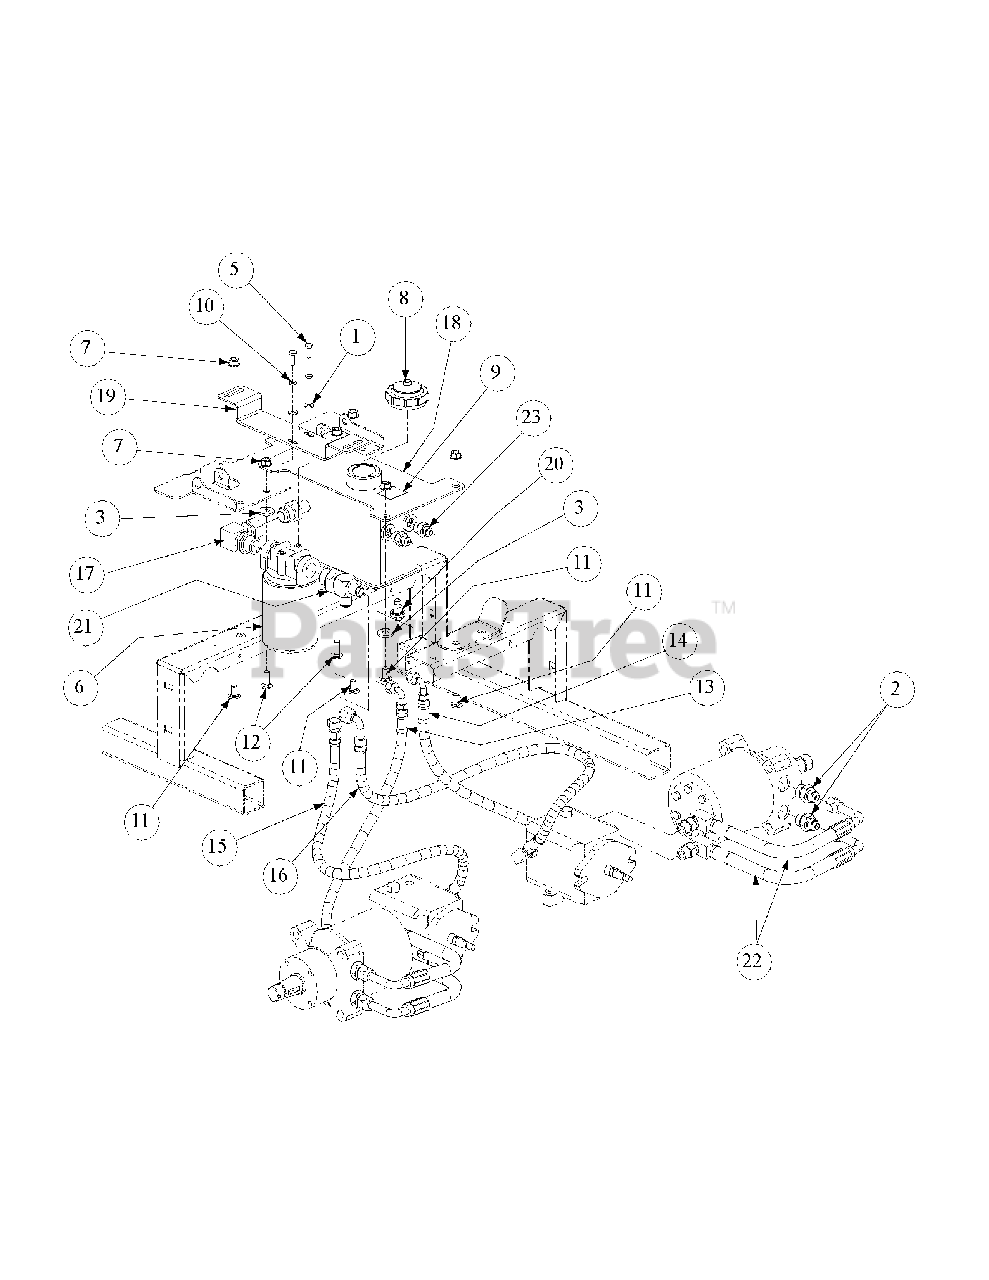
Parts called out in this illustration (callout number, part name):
1	Washer, 1/4
2	Fitting 1/2 x 3/4 - O Ring
3	Washer, .406 x 1.0 OD x .105
4	Cable Tie, 3/16 x .05 x 7.4
5	Hex Cap Screw, 1/4-20, .75
6	Filter Head 3/4
7	Hex Nut Flange Lock, 3/8-16
8	Cap, Hydro Oil Tank
9	Decal Oil Only 5W40
10	Lock Washer, 1/4
11	Carriage Bolt, 3/8-16 x .75 LG.
12	Carriage Bolt, 3/8-16 x 1.00
13	28.87" Return Hose Assembly
14	31.88" Return Hose Assembly
15	29.25" Supply Hose Assembly
16	40.31 Supply Hose Assembly
17	Fitting Elbow, 90
18	Hydraulic Tank Assembly
19	Filter Mounting Bracket
20	Oil Pan Drain w/ Seal and Plug
21	Tee Fitting, 3/4 x 1/2 x 1/2
22	Hydraulic Hose
23	Fitting 1/2 x 3/8
